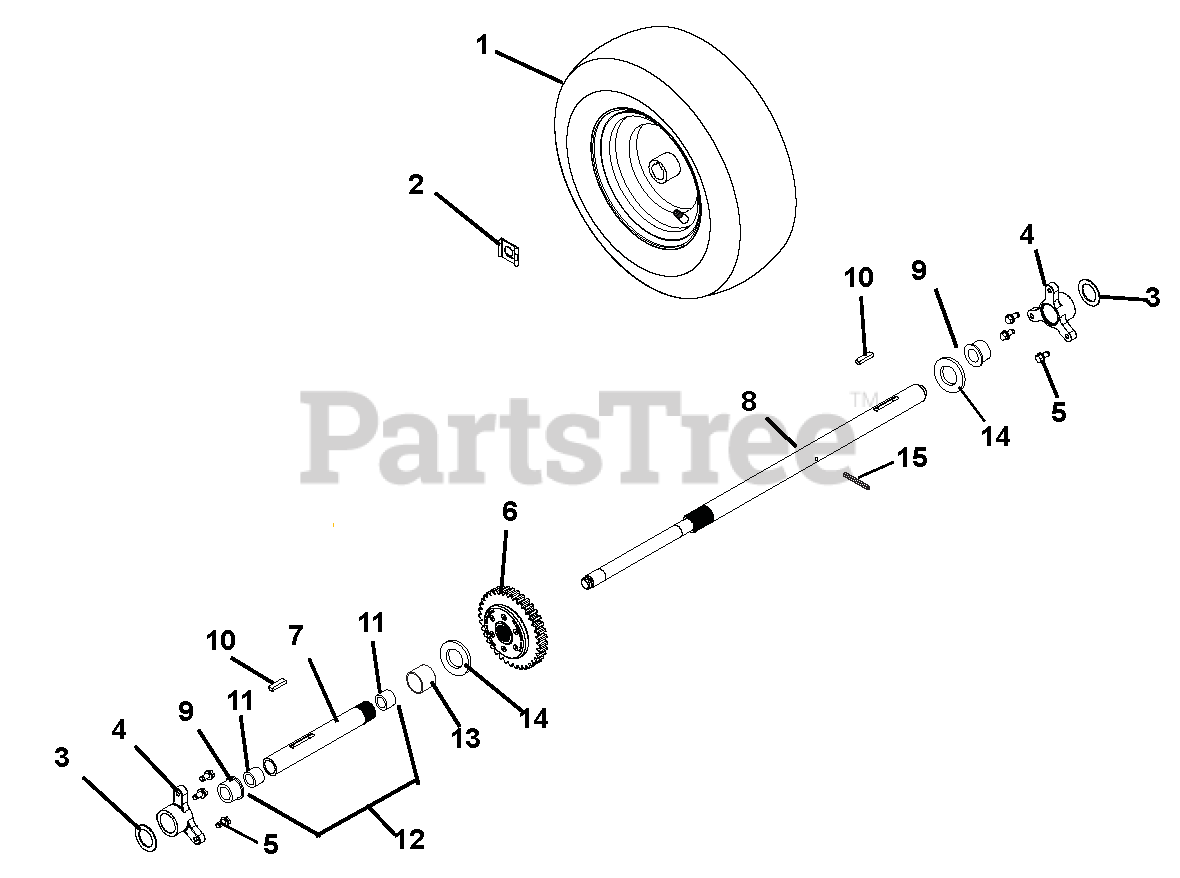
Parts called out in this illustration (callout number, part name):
1	TIRE/WHEEL,RH 15X5.00-6 REMOTE
2	CLIP, SNAP .625 DIA
3	WSHR-FL-STL 1.010X1.505X.062YZ
4	BUSHING, RAKE SHAFT 1"
5	@SCR-TAP .25-20X.50 HWH TR YWZ
6	DIFFERENTIAL, AUTOMATIC
7	AXLE, SHORT - DIFFERENTIAL
8	AXLE, LONG - DIFFERENTIAL
9	BSHG-FLG SPLIT NYLINER 1.0" HP
10	KEY-RECT .25X.188X1.00
11	BSHG-SLV .706X.764X.75 BRZ
12	AXLE, DIFFERENTIAL W/BUSHINGS
13	BSHG-SLV, 1.012X1.125X1.00
14	WSHR-FL-STL 1.010X1.505X.062YZ
15	PIN-ROLL .188X1.25
